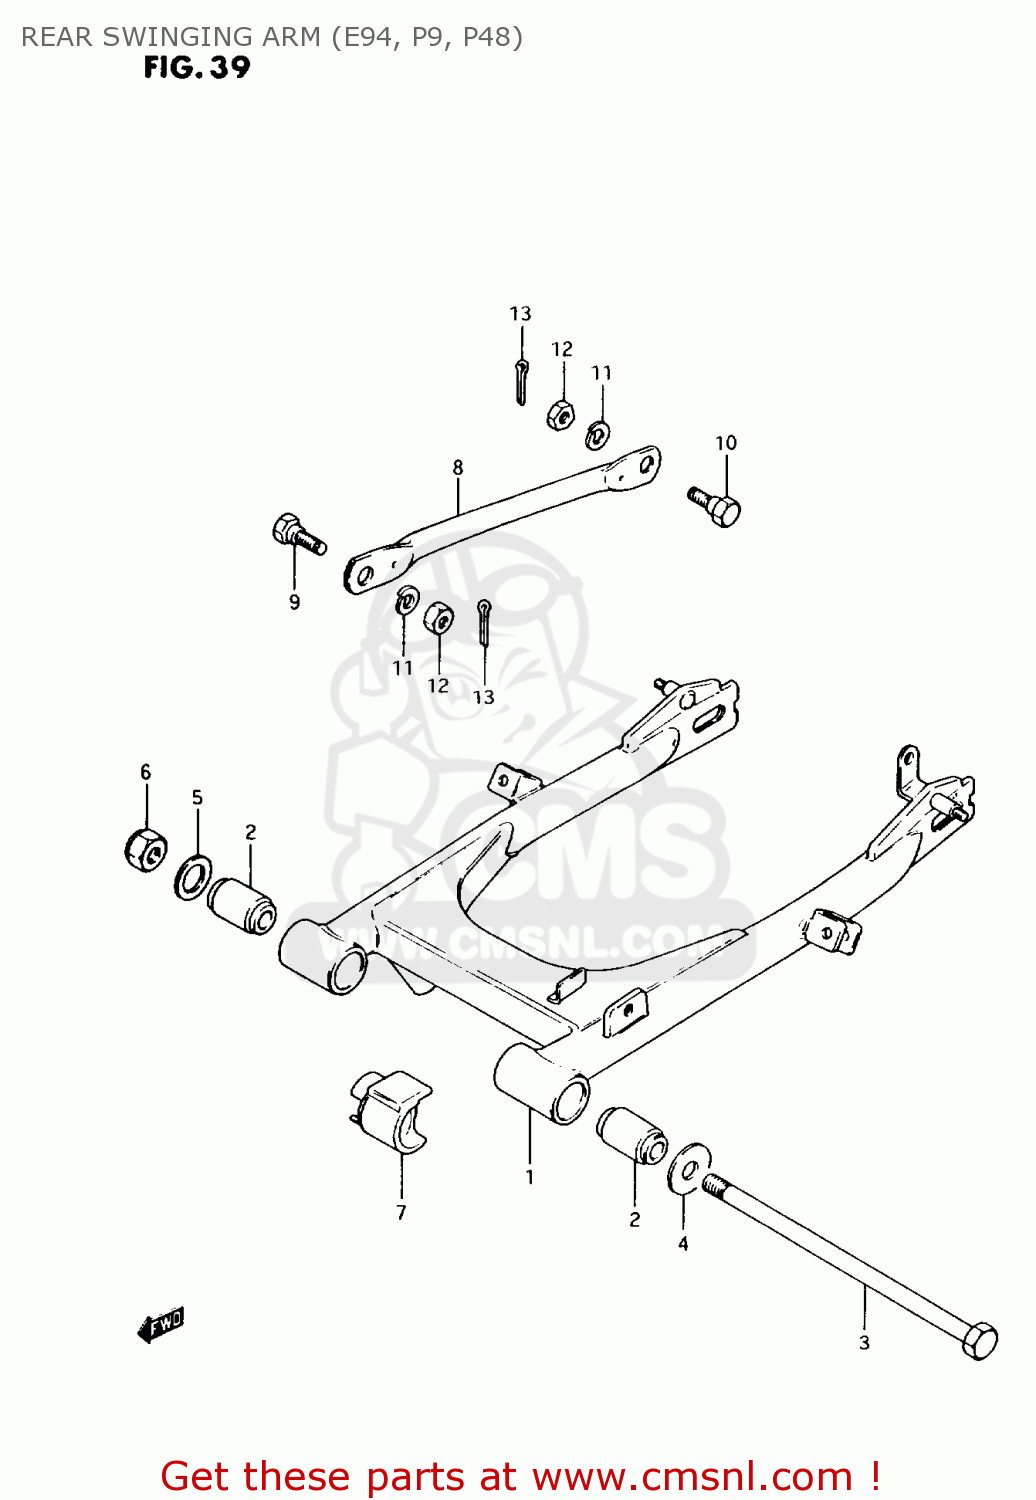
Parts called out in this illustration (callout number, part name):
1	SWINGING ARM SET (BLACK)
2	BUSH(12X24X44)
3	SHAFT,RR SWINGINGARM PIVOT
4	WASHER(12.5X32X2.3)
5	WASHER
6	NUT 12MM
7	BUFFER,DEFENSE
8	TORQUELINK,RR
9	BOLT(8X22.5)
10	BOLT(8X22.5)
11	WASHER,LOCK
12	NUT
13	PIN 20X20
